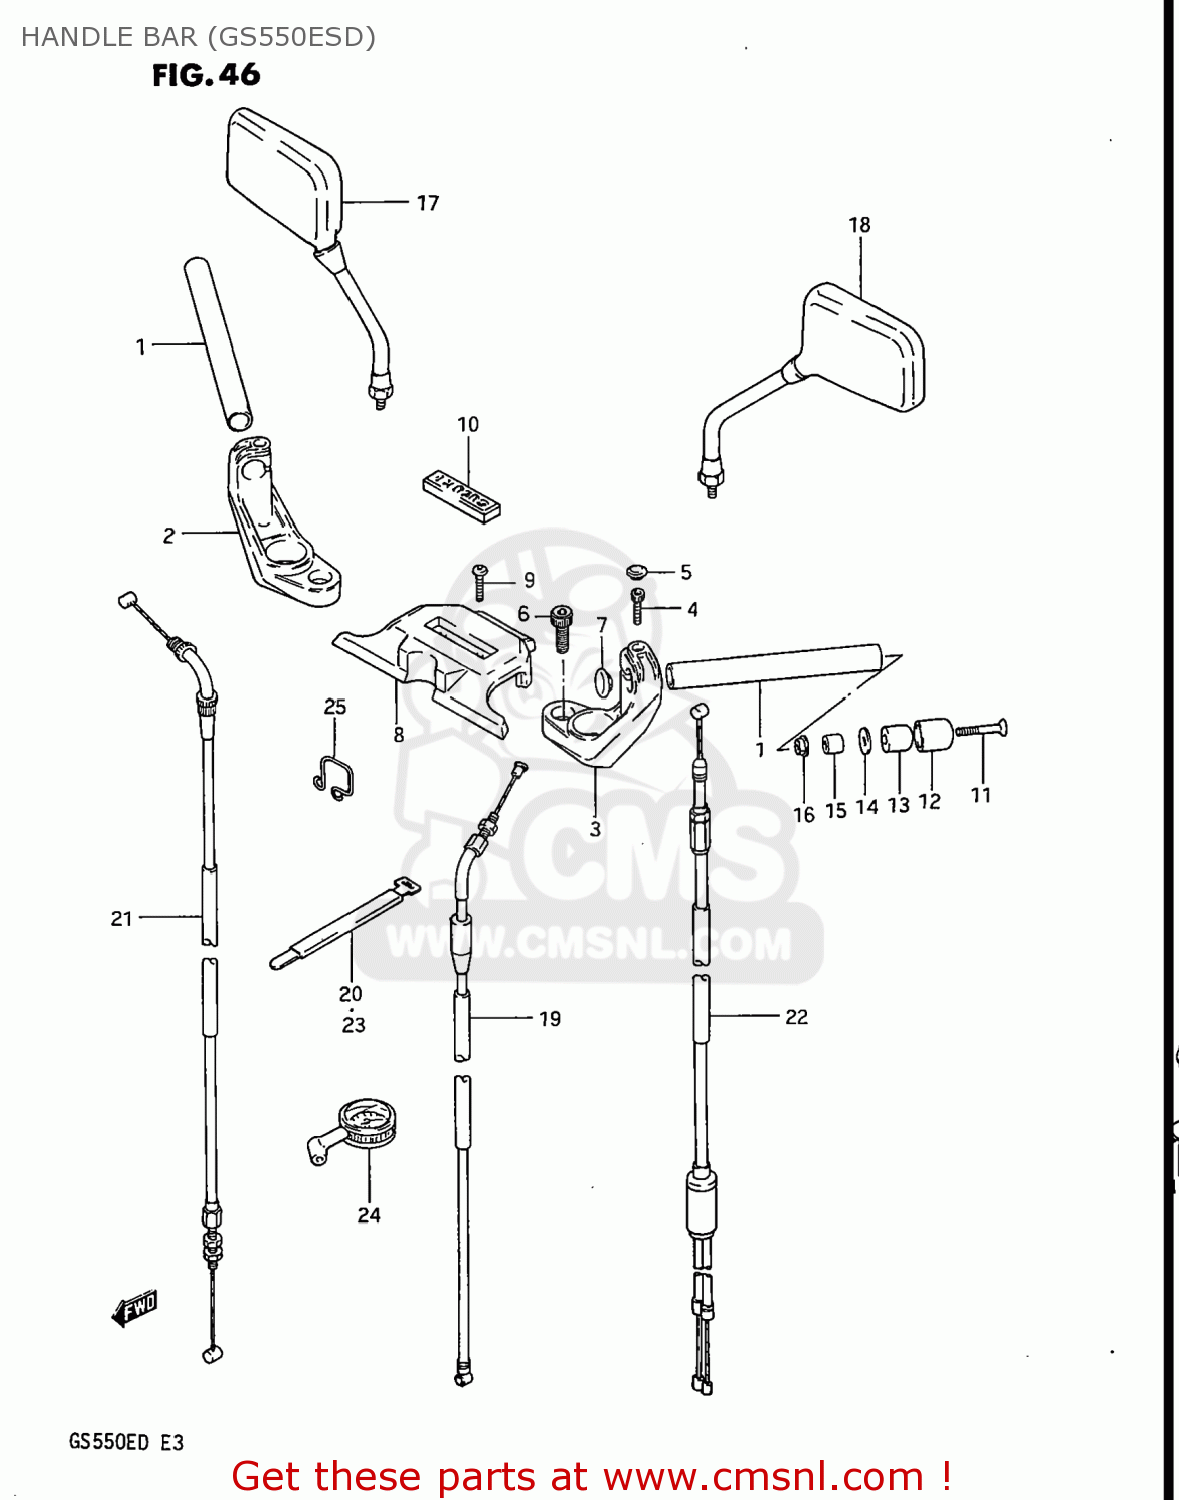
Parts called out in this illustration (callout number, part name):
1	HANDLEBAR
2	HOLDER,HANDLEBAR
3	HOLDER,HANDLEBAR
4	BOLT
5	CAP(OD:14.5)
6	BOLT
7	CAP,GRIP END
8	PAD,HANDLEBAR
9	SCREW
10	EMBLEM,HANDLE PAD
11	SCREW 6X55
12	CAP,BALANCER
13	BALANCER,HANDLEBAR
14	SPACER,BALANCER
15	EXPANDER,BALANCER
16	NUT
17	MIRROR ASSEMBLY,REAR VIEW
18	MIRROR ASSEMBLY,REAR VIEW
19	CABLE ASSY,CLUTCH
20	CLAMP
21	CABLE ASSEMBLY,THROTTLE
22	CABLE COMP,STARTER
23	CLAMP
24	GAUGE ASSY,AIR PRESSURE
25	GUIDE,CABLE/HARNESS
